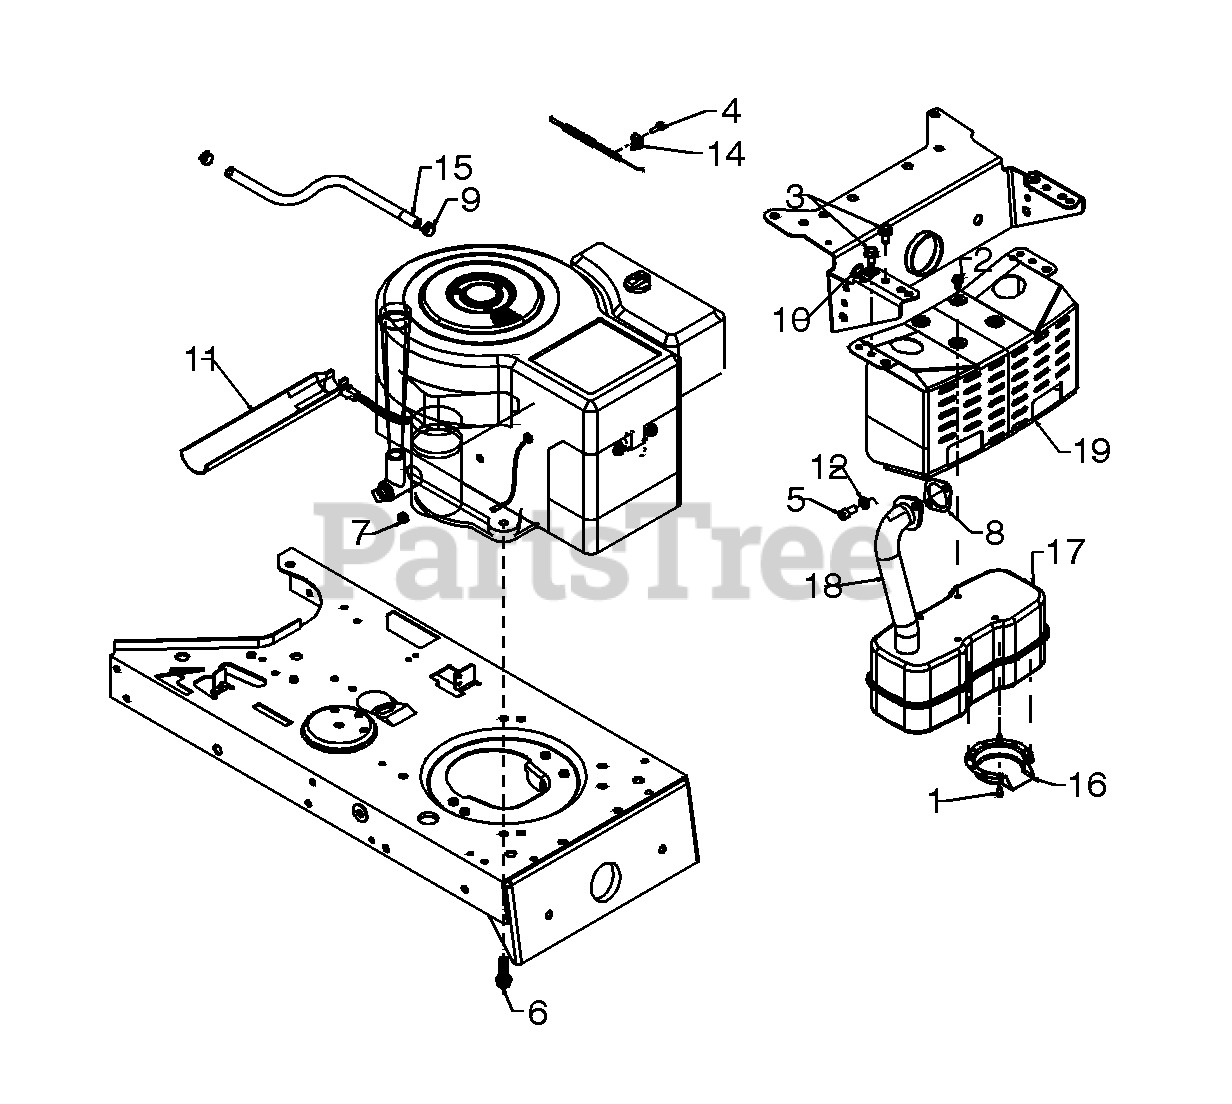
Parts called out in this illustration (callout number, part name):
1	Hex Slot Scr. #8-32 x .38" Lg.
2	Hex Wash. TT-Tap Scr. 1/4-20 x .5" Lg.
3	Hex Wash Hd. TT-Tap Scr. 5/16-18 x .62" Lg.
4	Scr. #10-32:.620 Hx. Slot Wash.
5	Socket Hd. Bolt 5/16-18 x .62" Lg.
6	Scr. 3/8-16 x 1.25
7	Nut, Hex 1/4-20
8	Exhaust Gasket
9	Hose Clamp .49 Dia.
10	Clamp 9/16 Dia.
11	Oil Drain Sleeve
12	L-Wash. 5/16" I.D.
14	Casing Clamp, Throttle, B&S
15	Fuel Line Hose
16	Muffler Deflector
17	Muffler
18	Exhaust Pipe
